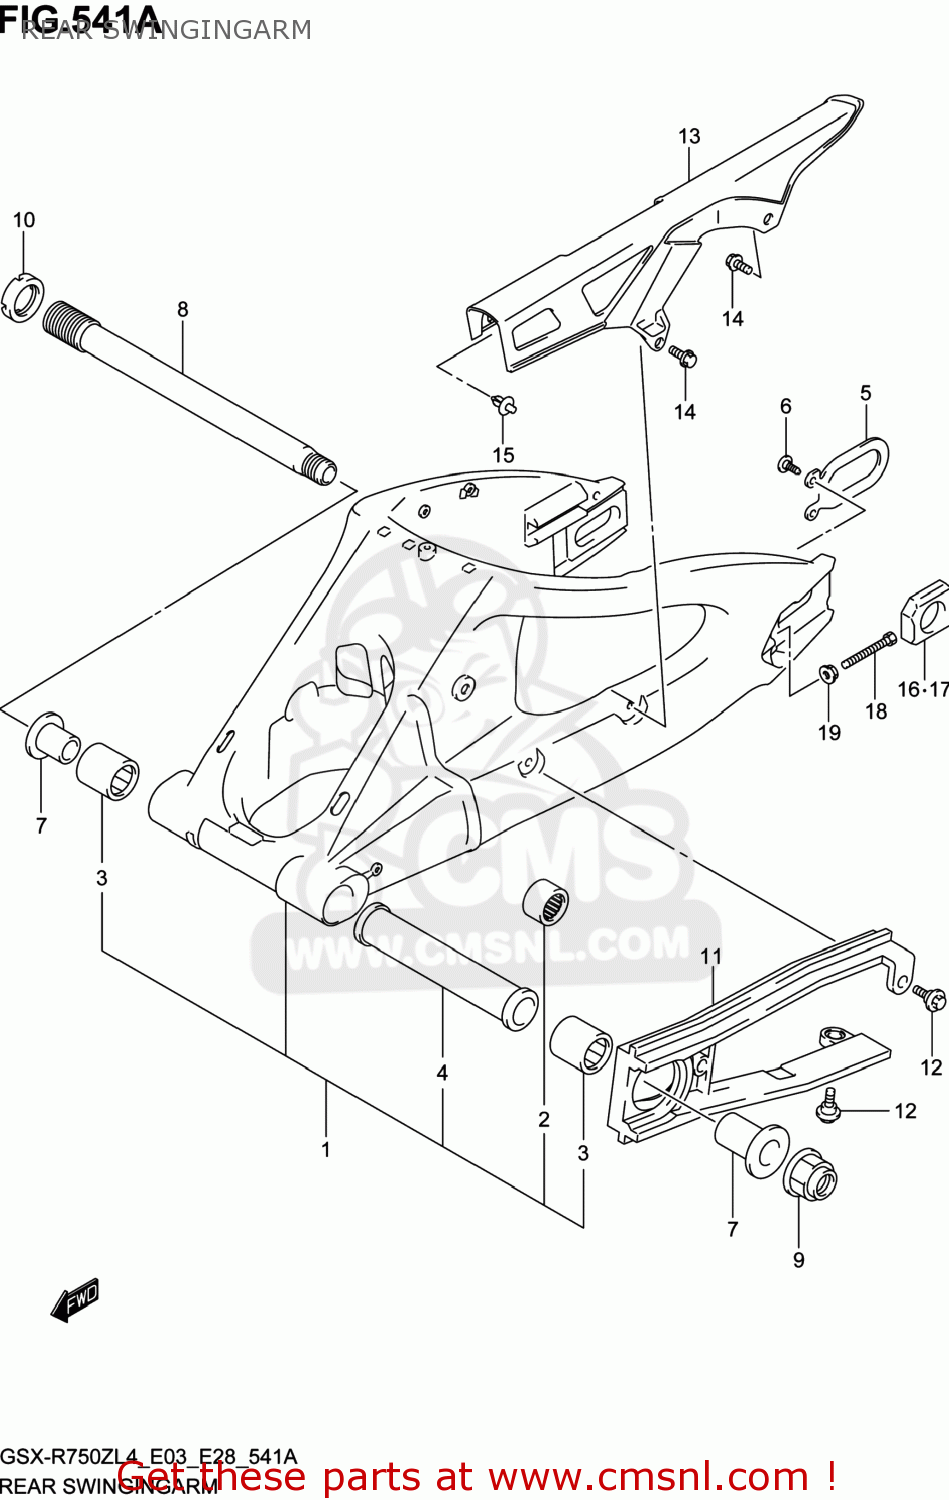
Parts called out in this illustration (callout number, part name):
1	SWINGINGARM ASSY,RR
2	BEARING(20X27X30)
3	BEARING(27X35X35)
4	SPACER,RR SWG PVT CTR
5	PLATE,RR SWING ARM BRKT
6	SCREW(6X12)
7	SPACER,RR SWGARM PIVOT BEARING
8	SHAFT,RR SWINGINGARM PIVOT
9	NUT
10	NUT,RR SWGARM PIVOT BOLT
11	BUFFER,CHAIN TOUCH DEFENSE
12	BOLT(6X17.8)
13	CASE,CHAIN
14	BOLT(6X12)
15	CLIP(BLACK)
16	ADJUSTER,CHAIN,R
17	ADJUSTER,CHAIN,L
18	BOLT(8X50)
19	NUT
